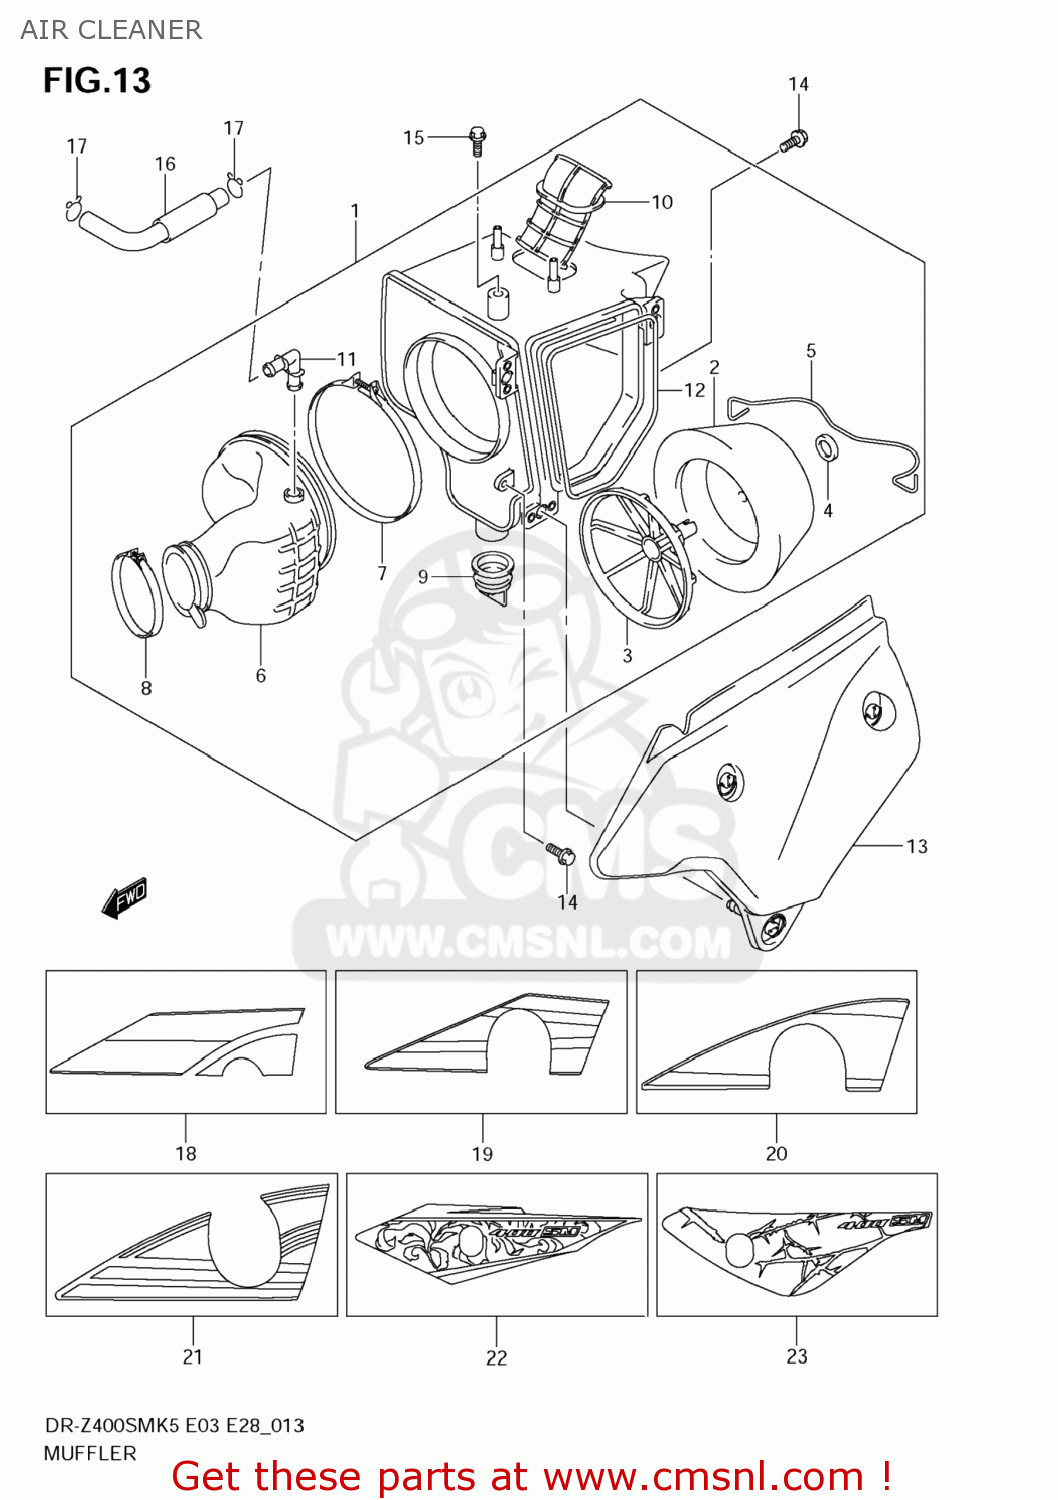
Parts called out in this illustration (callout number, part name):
1	CLEANER,AIR
2	FILTER ASSY
3	HOLDER,FILTER
4	SPACER
5	SPRING
6	TUBE,OUTLET
7	CLAMP
8	CLAMP
9	VALVE
10	TUBE,INLET
11	JOINT
12	GASKET,AIR CLEANER (NAS)
13	CAP,AIR CLEANER
14	BOLT
15	BOLT(6X14.6)
16	TUBE,BREATHER
17	CLIP
18	TAPE SET,CAP AIR CLEANER
19	TAPE,AIR CLNR CAP
20	TAPE,AIR CLNR CAP
21	TAPE,AIR CLNR CAP
22	TAPE,AIR CLNR CAP
23	TAPE,AIR CLNR CAP
